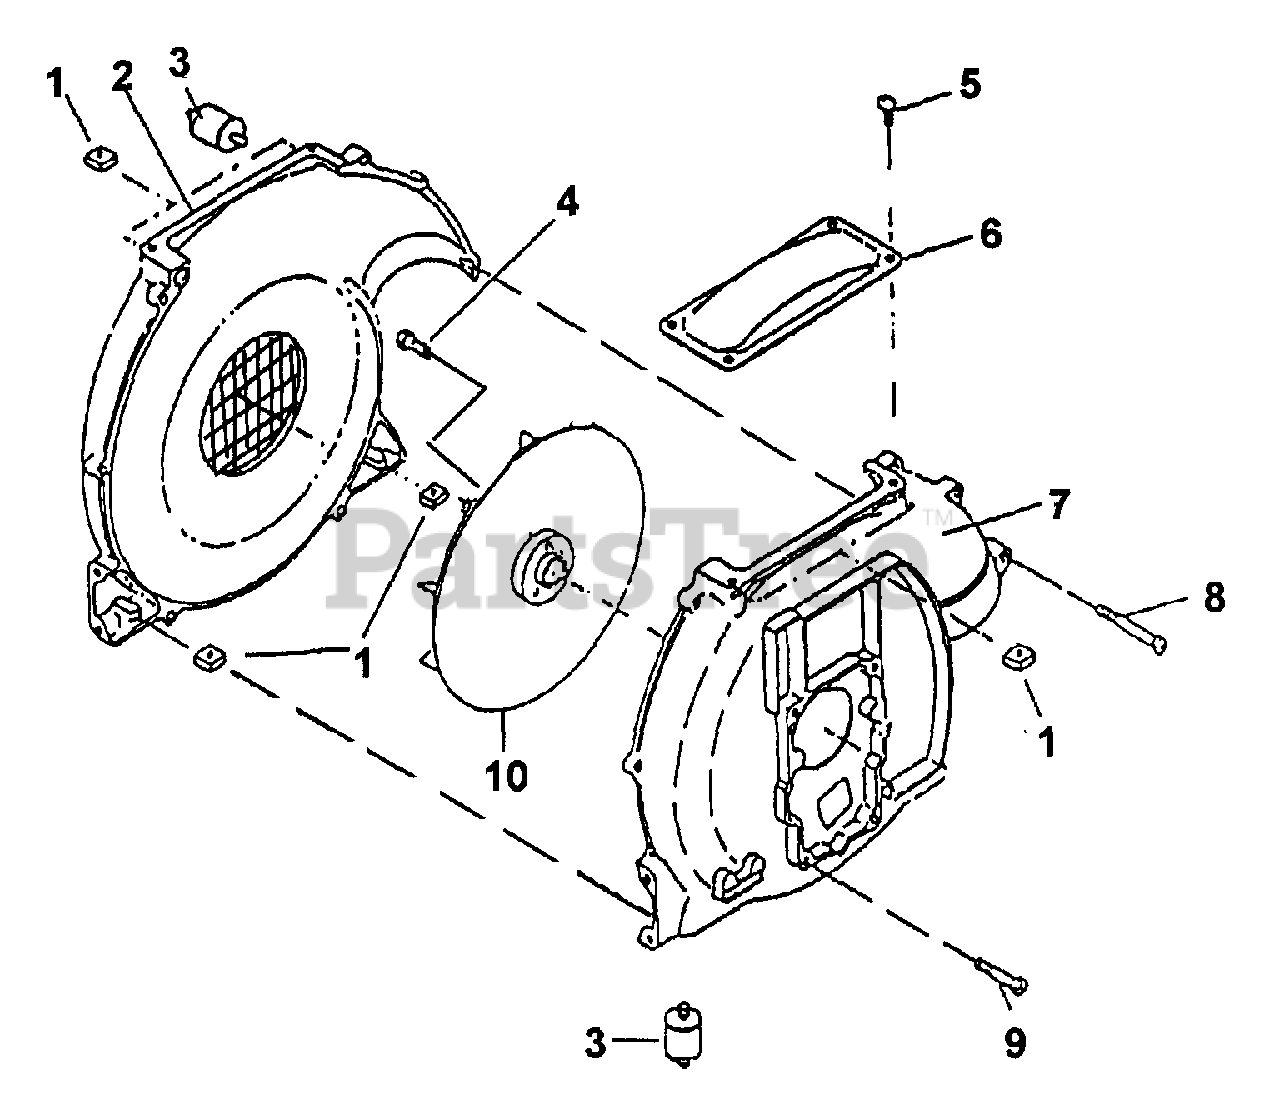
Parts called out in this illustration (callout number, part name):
2	FAN CASE, FRONT
3	ANTI-VIBE INSULATOR
4	SCREW
5	SCREW
7	FAN CASE, REAR
8	SCREW
9	SCREW
